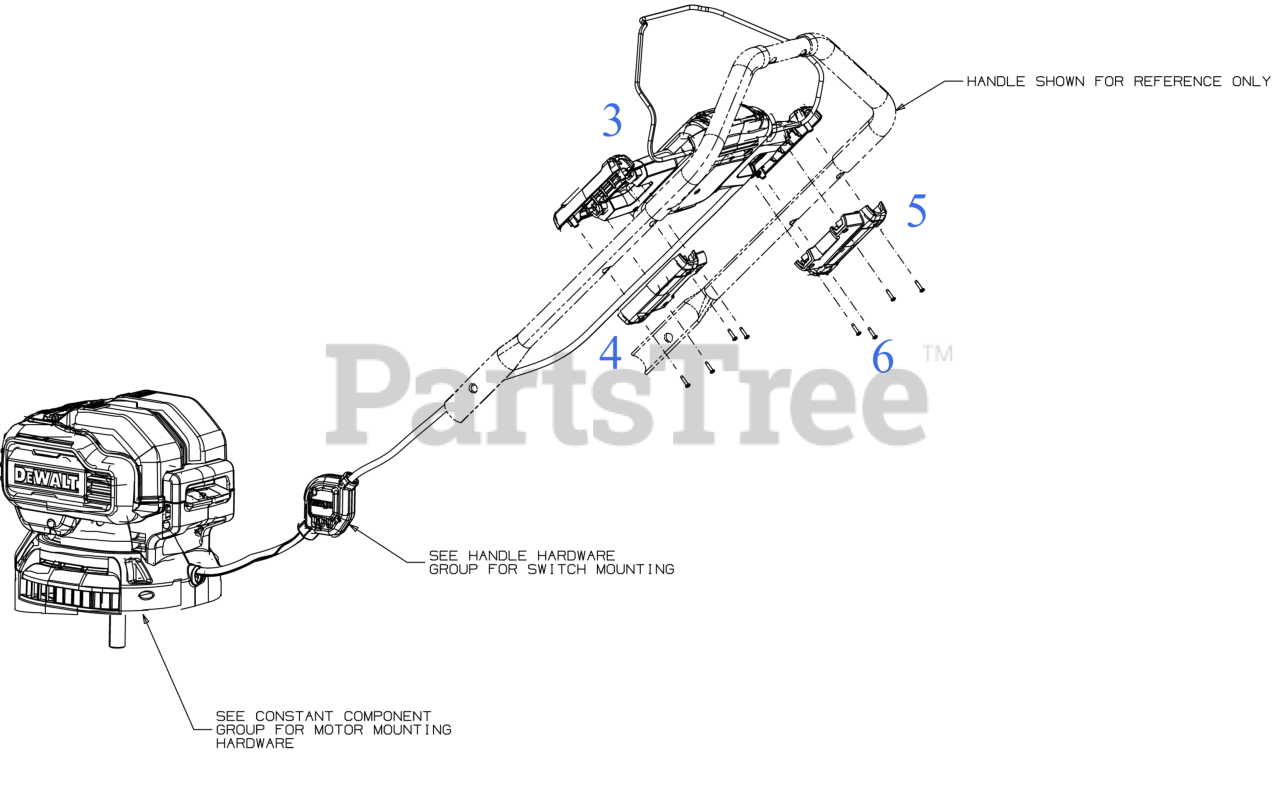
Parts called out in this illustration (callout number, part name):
3	MTR ASM:RWD:HNDL PNL
4	HANDLE PANEL COVER (REAR) (LH) (YELLOW)
5	HANDLE PANEL COVER (REAR) (RH) (YELLOW)
6	SCREW-TAP PLASTIC #6-19 X 0.62
